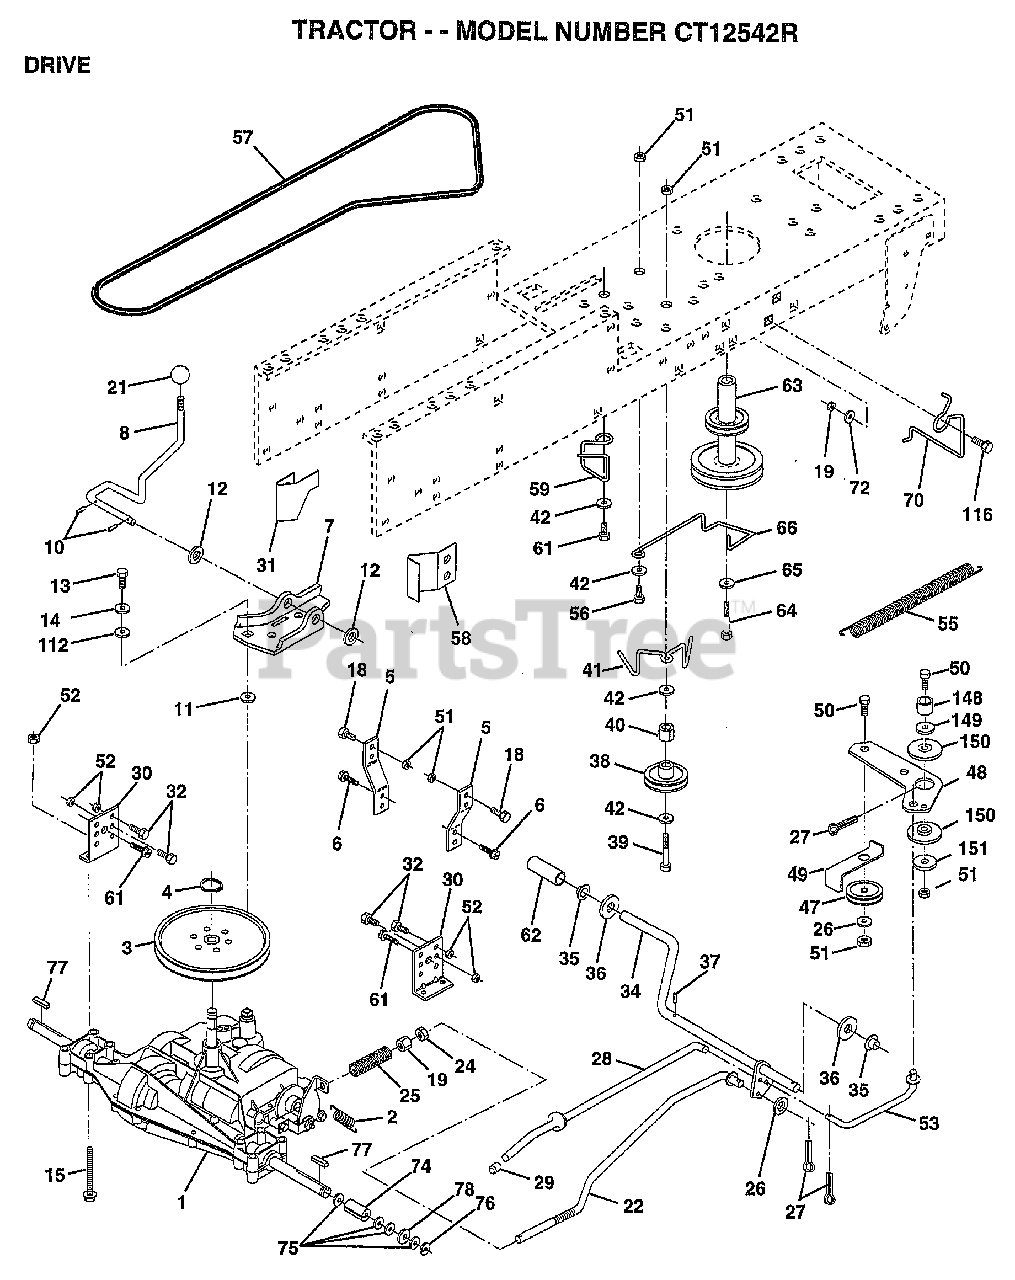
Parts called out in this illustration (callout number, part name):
2	SPRING.BRAKE.RETU
3	PULLEY TRANS
5	STRAP TORQUE
6	SCREW
7	BRKT.SADDLE.SHIFT
8	SHIFT ROD
9	PIN COTTER 1/8
11	WASH-SHFT PLT LT
12	WASHER
13	BOLT.1/4-28.W/PAT
14	LOCKWASHER
15	BOLT.HX.FLG.5/16
18	BOLT
19	NUT
21	KNOB T (1/2-HOLE)
22	BRAKE ROD
24	NUT
25	SPRING ROD LT
26	WASHER
27	COTTER PIN
28	ROD.BRAKE.PARK.LT
29	PLUNGER CAP T
30	TRANSAXLE MTG BKT
31	"KEEPER,BELT LH T"
32	BOLT
34	SHAFT ASM-PEDAL F
35	NYLON BEARING
36	WASHER LT
38	PULLEY.IDLER.FLAT
39	BOLT
40	SPACER T
42	WASHER
48	BELLCRANK.CLUTCH
49	RETAIN BELT
53	"LINK, CLUTCH T"
55	"SPRING, RETURN LT"
57	"V-BELT,95.3"
58	"KEEPER,BELT RH T"
59	KEEPER BELT CNTSP
61	SCREW
62	PEDAL COVER T
63	PULLEY.ENGINE
64	BOLT
65	LOCKWASHER
66	KEEPER-BELT
70	KEEPER BELT ENG
72	WASHER
74	SPACER LT
76	E-RING LT
77	SQUARE KEY
78	WASHER
112	WASHER LT
116	BOLT RDHD 3/8-16
149	SPACER RETAINER
150	BUSHING.NYLON
151	WASHER
